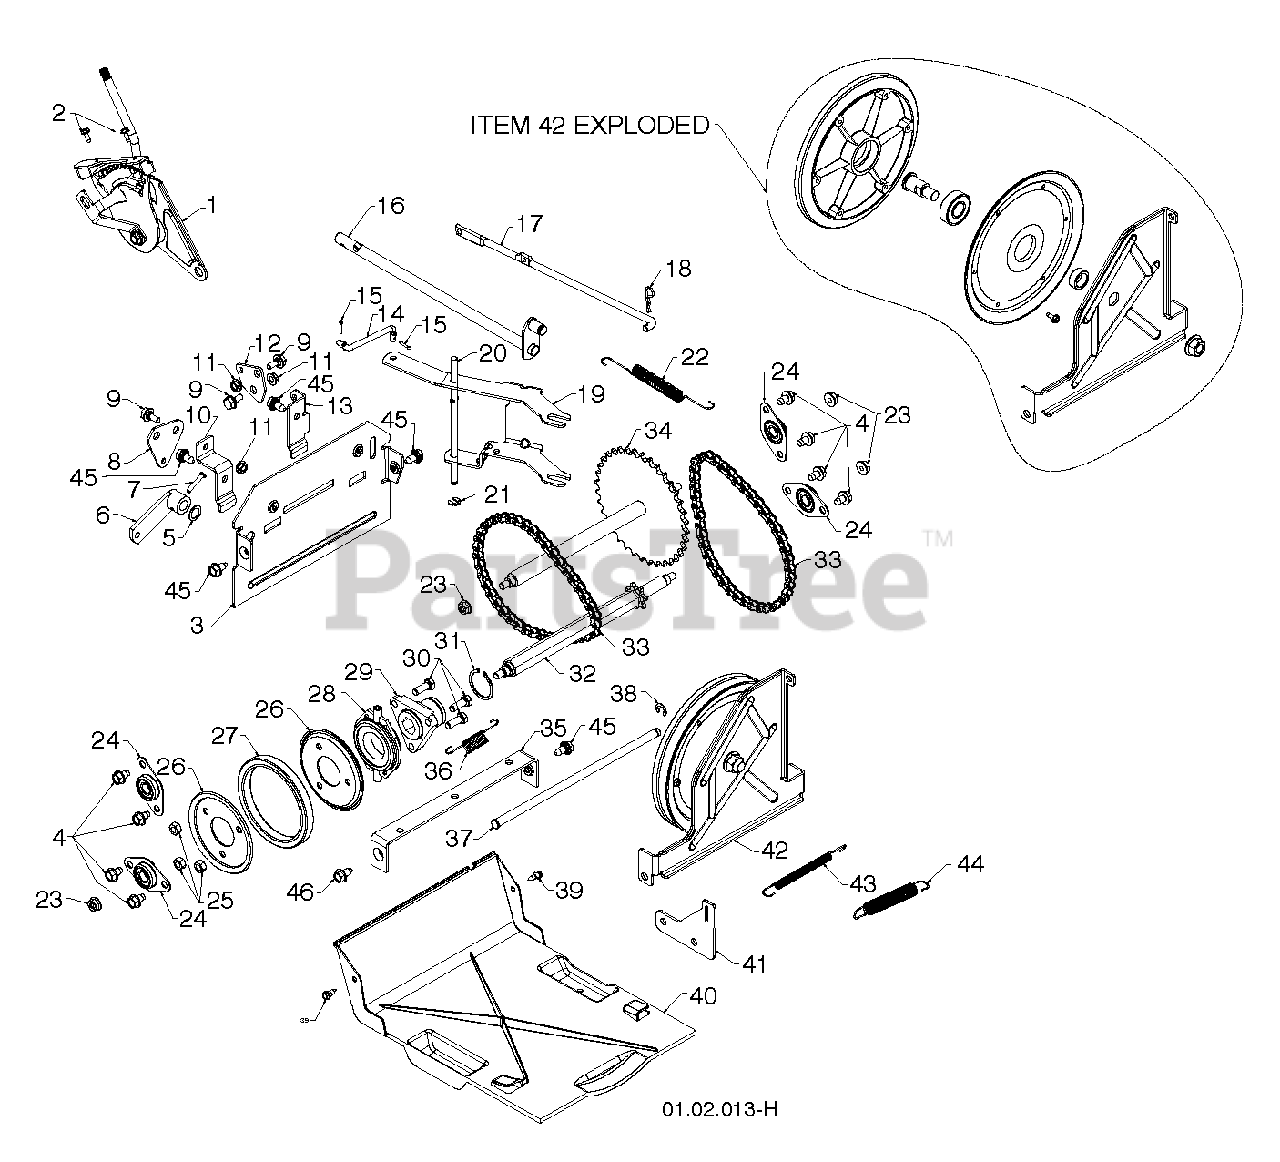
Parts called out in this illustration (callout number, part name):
1	HEAD ASSY SPEED
3	PLATE.END.CHAIN.ASM.PNT.ORANGE
4	SCREW LT
5	THRUST WASHER
6	ARM, AUGER CONTROL
7	CLEVIS PIN
8	PLATE.SHIFTER.BZP
9	BOLT.SHOULDER.3/X.25
10	BRACKET.SHIFTER.PLATE.BZP
11	NUT.HEX.FLANGE.1/4
12	PLATE.CLUTCH.BZP
13	BRACKET.CLUTCH.PLATE.BZP
14	LINK, SPEED CONTROL
15	RETAINER CLIP
16	CONTROL.SHAFT.ASM
17	ROD.CLUTCH.SWING.PLATE
18	SPRING RETAINER
19	BRACKET.YOKE.SHIFTER.BLACK
20	ROD.PIVOT.SHIFTER
21	KLIP RING TI
22	SPRING.TRACTION.RETURN
23	NUT.LOCK.5/16-18
24	BEARING FLANGE BALL
25	NUT.CENTERLOCK.5/16-
26	PLATE.RUBBER.WHEEL
27	RING.RUBBER.4.5".SNOW.DR(2 2MC
28	TRUNNION BEARING ASSY
29	HUB, RUBBER WHEEL
30	BOLT
31	RETAINING RING (2 2)(3 2)
32	SHAFT.HEX.W/SPOCKET
33	CHAIN.DRIVE.SNOWTHROWER.#420
34	SPROCKET.WELDMENT
35	SHIFTER BRACKET
36	SPRING, BIAS
37	ROD.PIVOT.SWING.PLATE.SNOW
38	E-RING.RETAINER.REINFORCED.375
39	SCREW, HEX HEAD, TAPPING
40	PAN.BOTTOM.PLASTIC
41	Traction Spring Bracket
42	PULLEY.PLATE.ASM.DRIVE
43	SPRING.TRACTION.IDLER
44	SPRING, BRAKE
45	BOLT.HEX.HD.WASHER.5/16-18X.75
46	BOLT.5/16HEX.WHS.HD
